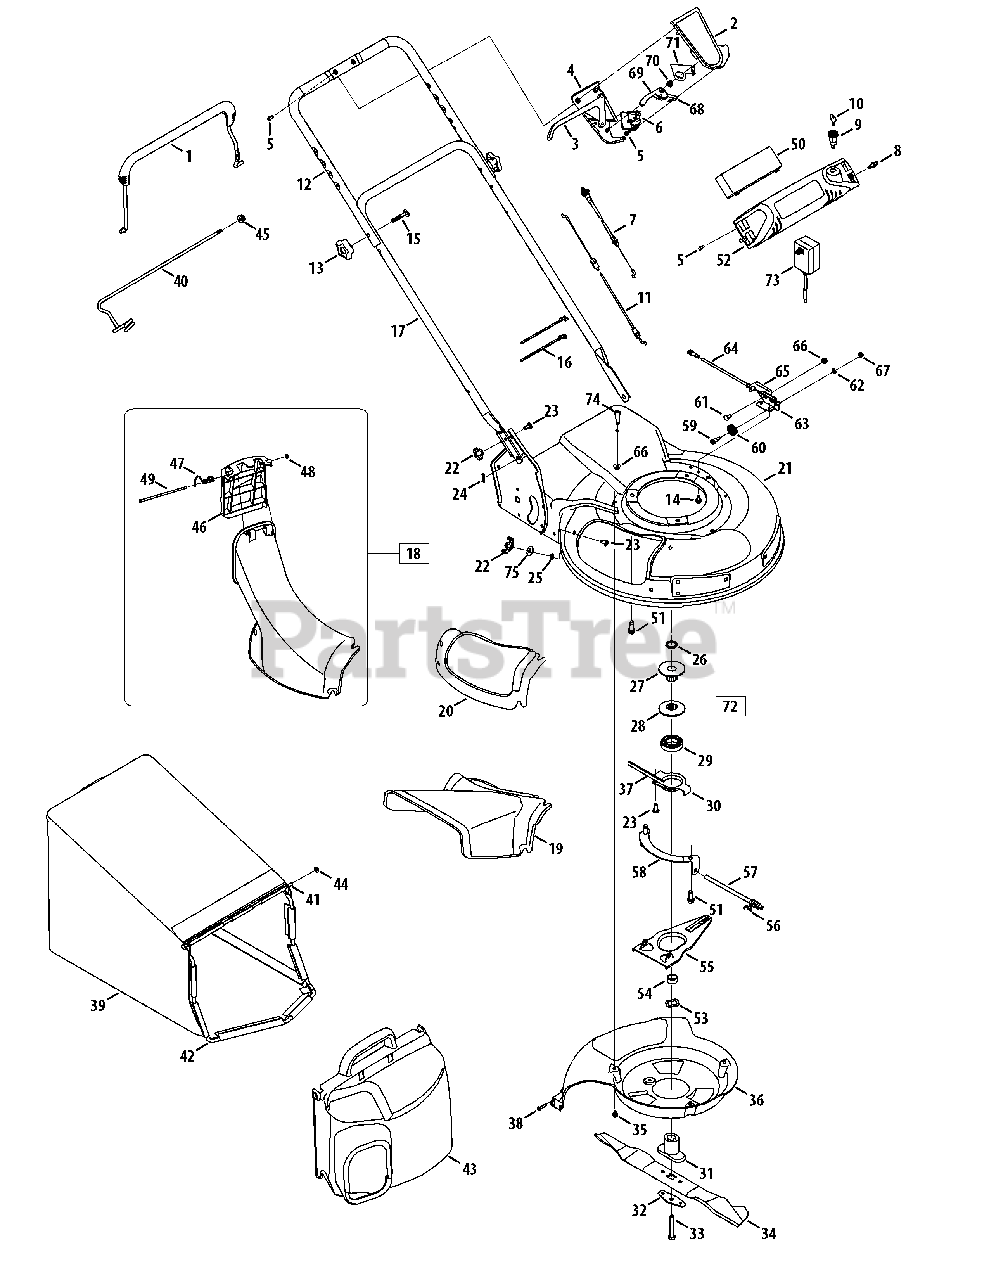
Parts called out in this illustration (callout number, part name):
1	Blade Control
2	Upper Control Housing
3	Drive Control
4	Lower Control Housing
5	C Sunk Tap Screw, #10 x.75 Lg
6	Cable Mounting Cap
7	Drive Cable
8	Rivet
9	Key Switch
11	Control Cable
12	Upper Handle
13	Star Knob
14	Screw, 1/4-20 x .625
15	Carriage Bolt, 5/16-18 x 2.0
16	Cable Tie
16	Guide, Cable
18	Adapter Assembly
19	Side Discharge Chute
20	Mulch Cover
22	Wing Nut
23	Carriage Bolt, 1/4-20 x .75"
24	Cotter Pin
25	Push Nut, .25 x ID x .50 OD
26	Sleeve Spacer, .88ID x 1.13OD
27	Half Pulley: 2.62 OD
28	Half Pulley: 2.62 OD x 1.61
29	Ball Bearing
31	Blade Adapter
32	Blade Bell Support
33	Hex Bolt, 3/8-24 x 2.5
34	21" Mulching Blade
35	Screw, 1/4-20 x 3.75
36	Baffle
37	Belt, 3/8 x 39.24
38	Screw, 1/4-15 x .750
39	Grass Catcher
40	Support Rod w/ Rope Guide
41	Pivot Rod
42	Grass Catcher Frame
43	Grass Catcher Cover
44	Cap Nut
45	Flange Lock Nut, 5/16-18
46	Chute Door
47	Torsion Spring
48	Push Cap
49	Pivot Rod
50	12V Battery
51	Sems Screw, 3/8-16 x 1.00
52	Harness Assembly
53	Wave Washer, 1.38 ID x.88 OD
54	Slve Spacer, .88 ID x 1.00 OD
57	Pivot Shaft
59	Shlder Screw, .375 ID x 1/4-14
60	Cable Roller
61	Carriage Screw, 1/4-20 x .62
62	Lock Washer, 1/4
63	Cable Mounting Bracket
64	6 Speed Cable
65	Cable Adjustment Bracket
66	Hex Nut 1/4-20
67	Hex Nut 1/4-28
68	Shift Lever Spring
69	6 Speed Shift Lever
70	Gear Insert
71	6 Spd. Rack Cable Bracket
72	Pulley Assembly (Incl Ref No. 27-30)
73	12V Battery Charger
74	Screw, 1/4-20 x 1.00
75	Flat Washer, .260 x .720 x .060
